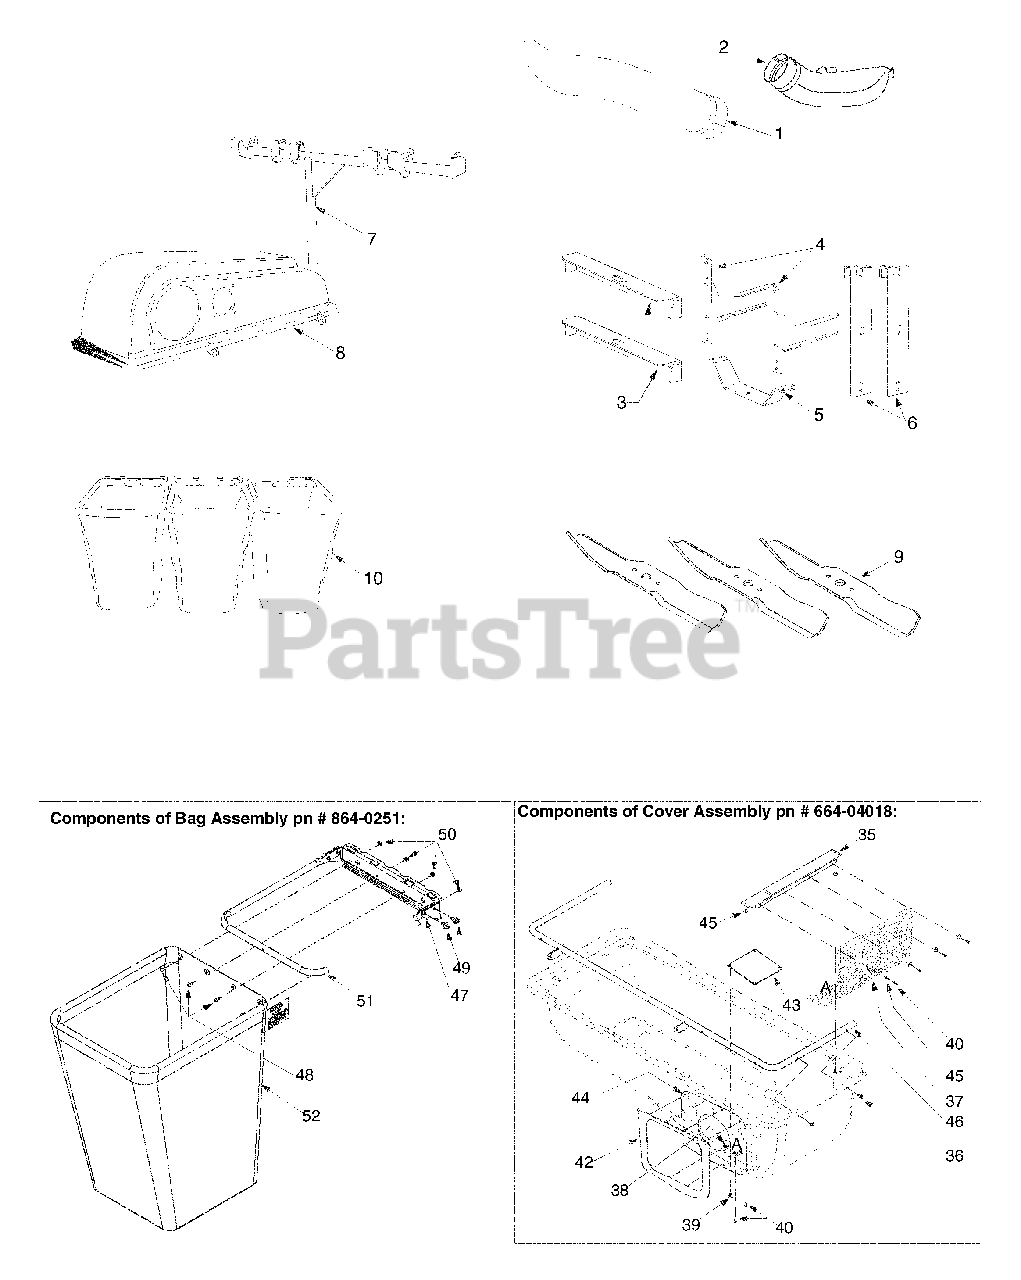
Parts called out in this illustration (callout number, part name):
1	Chute Tube
2	Discharge Chute Assembly
9	Hi-Lift Blade
10	Grasscatcher Bag Assembly
37	Screen
38	Push Nut
39	Ratchet Clip
40	Pop Rivet
42	Retainer Seal
43	Plastic Plate
44	Grass Bag Seal
45	Flat Washer
48	Machine Screw
49	TTScrew 5/16-18 x 0.625
50	Hex Sems Nut
